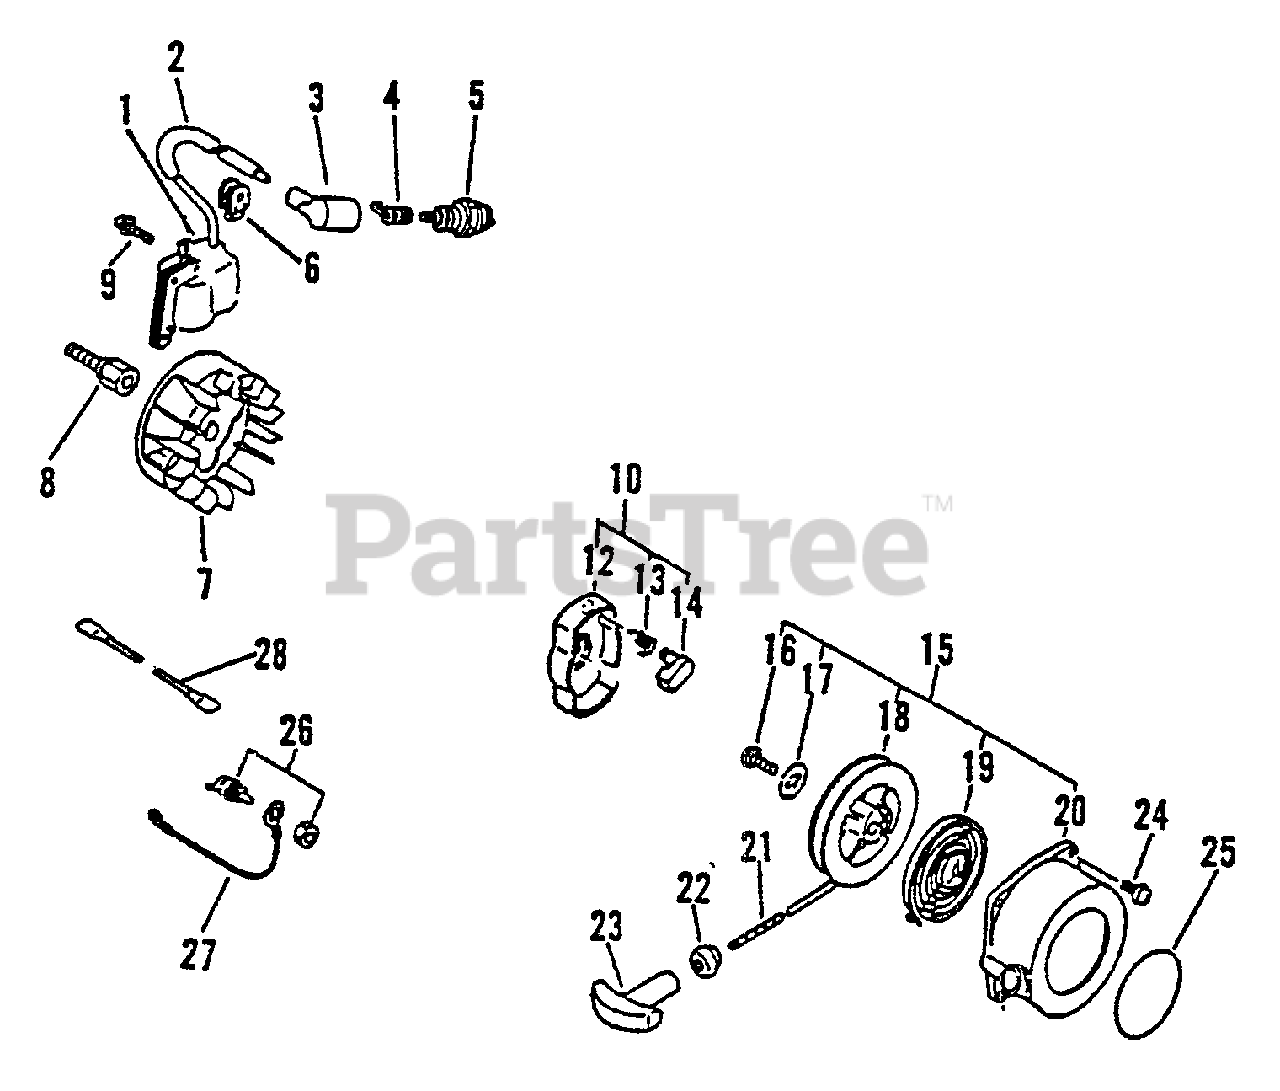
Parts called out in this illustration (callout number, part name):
1	COIL, IGNITION
3	CAP, SPARK PLUG
4	TERMINAL, SPARK PLUG CAP
5	SPARK PLUG -- BPM-7A
5	SPARK PLUG -- BPMR-7A
7	FLYWHEEL
8	HUB, FAN
9	SCREW - 4X22
10	STARTER PAWL ASSY
12	CATCHER, PAWL
13	SPRING, RETURN
14	PAWL, STARTER - BLACK
15	STARTER ASSY
17	WASHER
18	REEL, ROPE
19	SPRING, REWIND
20	CASE, STARTER
21	ROPE, STARTER - 3X1000
22	GUIDE, ROPE
23	GRIP, STARTER
24	SCREW - 4X18
25	LABEL - ECHO
26	IGNITION SWITCH ASSY
27	LEAD - GROUND
28	LEAD - GROUND
